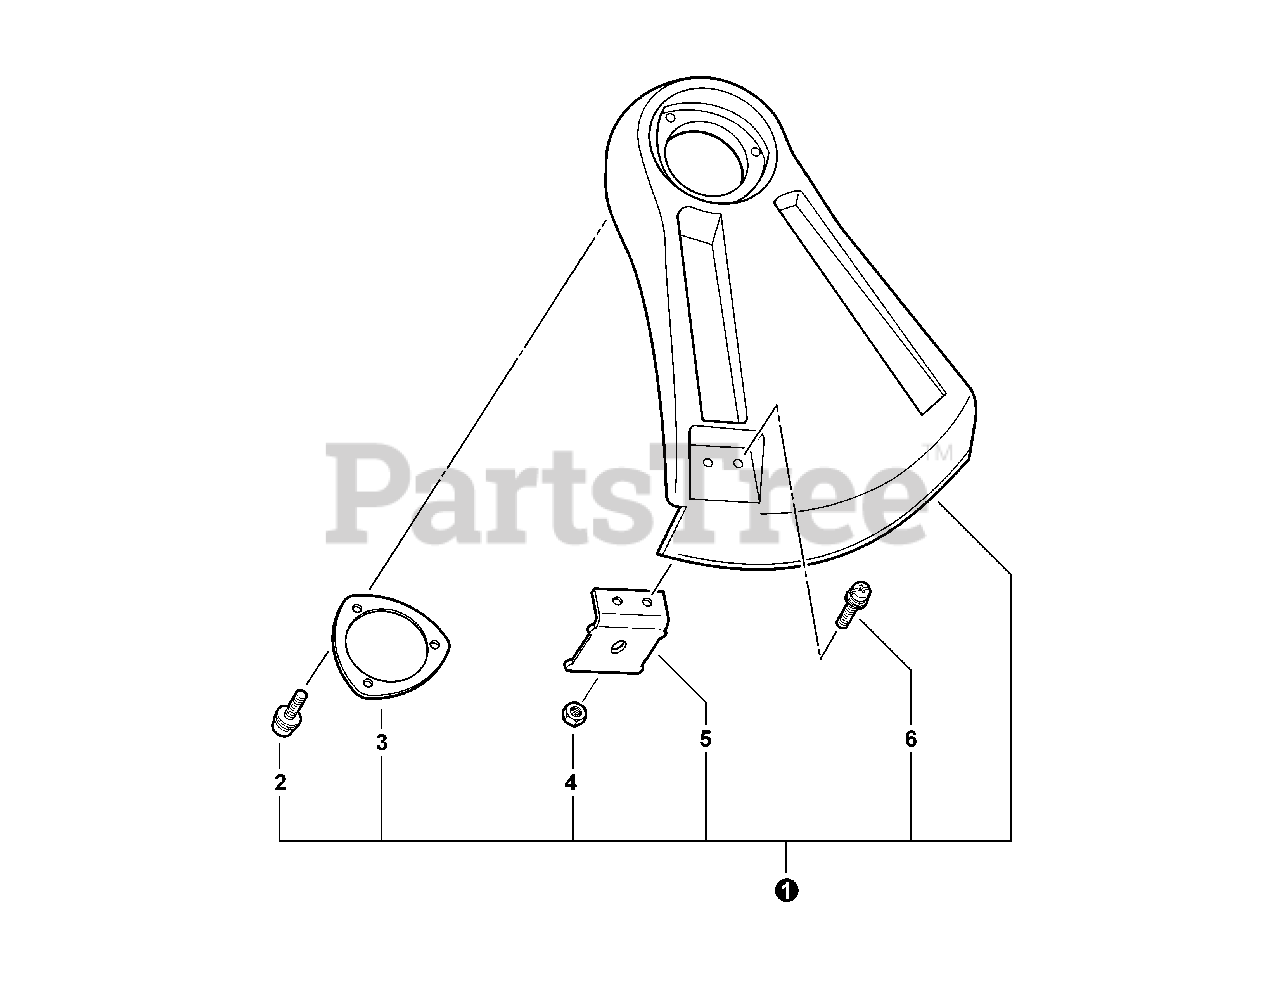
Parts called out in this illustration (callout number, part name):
1	SHIELD ASY
2	SCREW 5×16
3	BRACKET, SHIELD
5	CUTTER
6	SCREW 5×12
